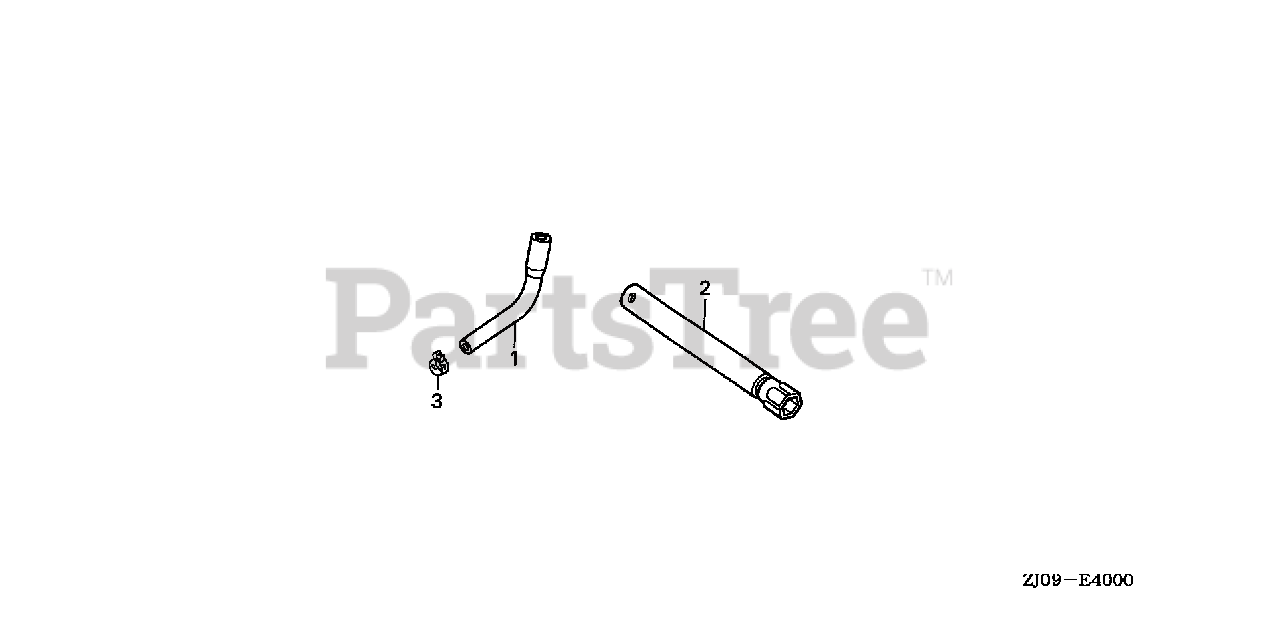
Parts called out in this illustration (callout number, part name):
1	TUBE, FUEL
2	WRENCH, SPARK PLUG
3	CLIP, TUBE (10.5MM)
